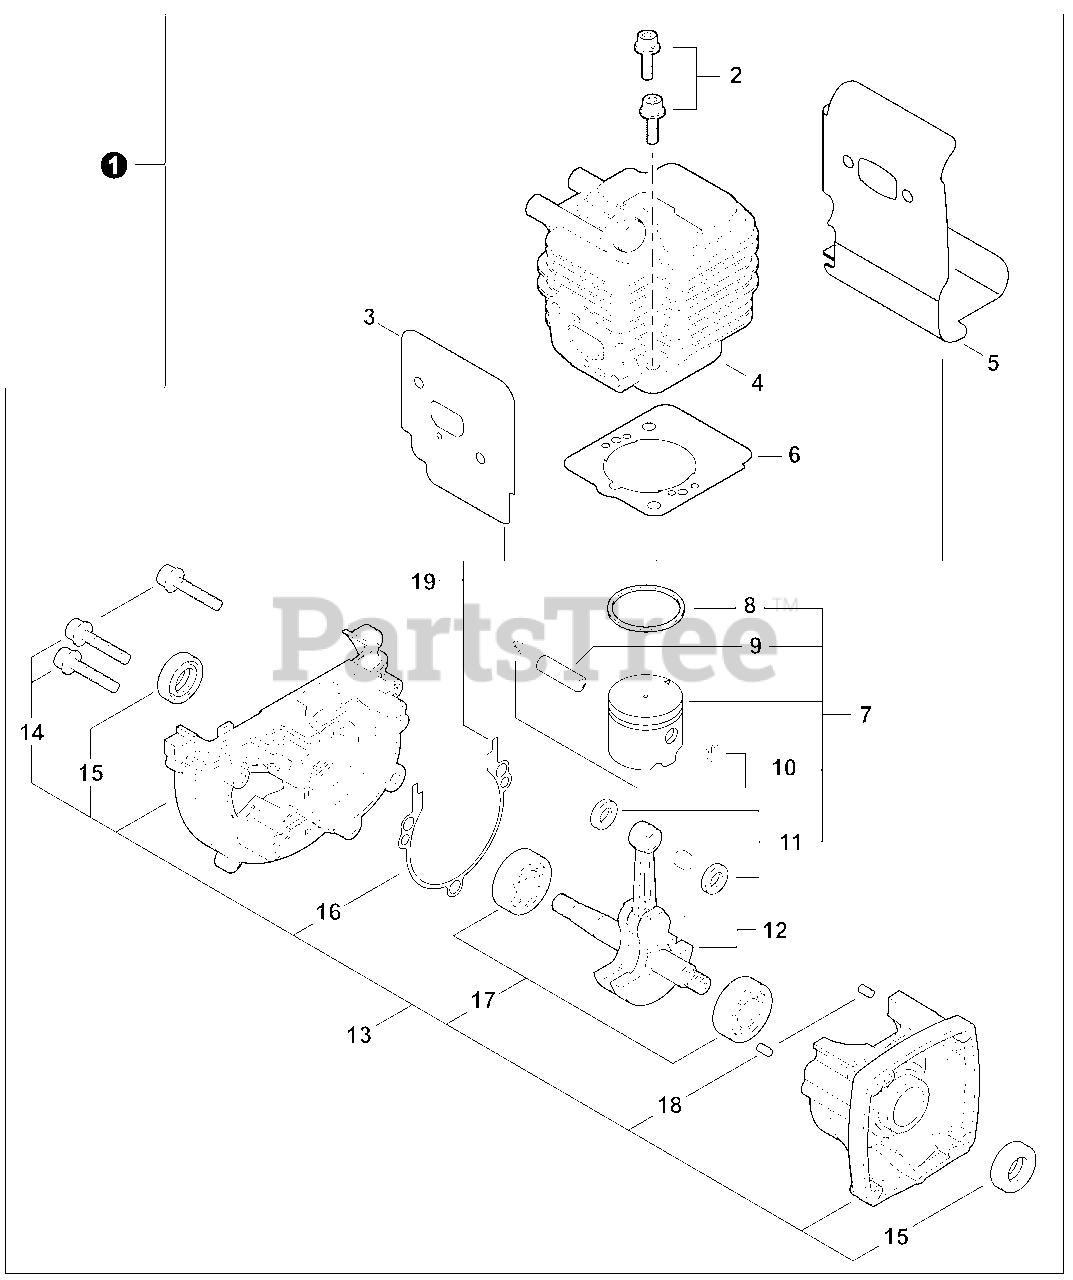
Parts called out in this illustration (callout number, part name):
1	SHORT BLOCK
2	BOLT 5×22
3	GASKET, INTAKE
4	CYLINDER
5	GASKET, EXHAUST
6	GASKET, CYLINDER
7	PISTON KIT
8	RING, PISTON
9	PIN, PISTON 5×8×25.5
10	RING, SNAP
11	WASHER, THRUST 8.2×13×0.5
12	CRANKSHAFT ASSY
13	CRANKCASE KIT
14	BOLT 5×28
15	SEAL, OIL 12
16	GASKET, CRANKCASE
17	BEARING, BALL 6201
18	PIN, LOCATING 4×8
19	GASKET KIT
